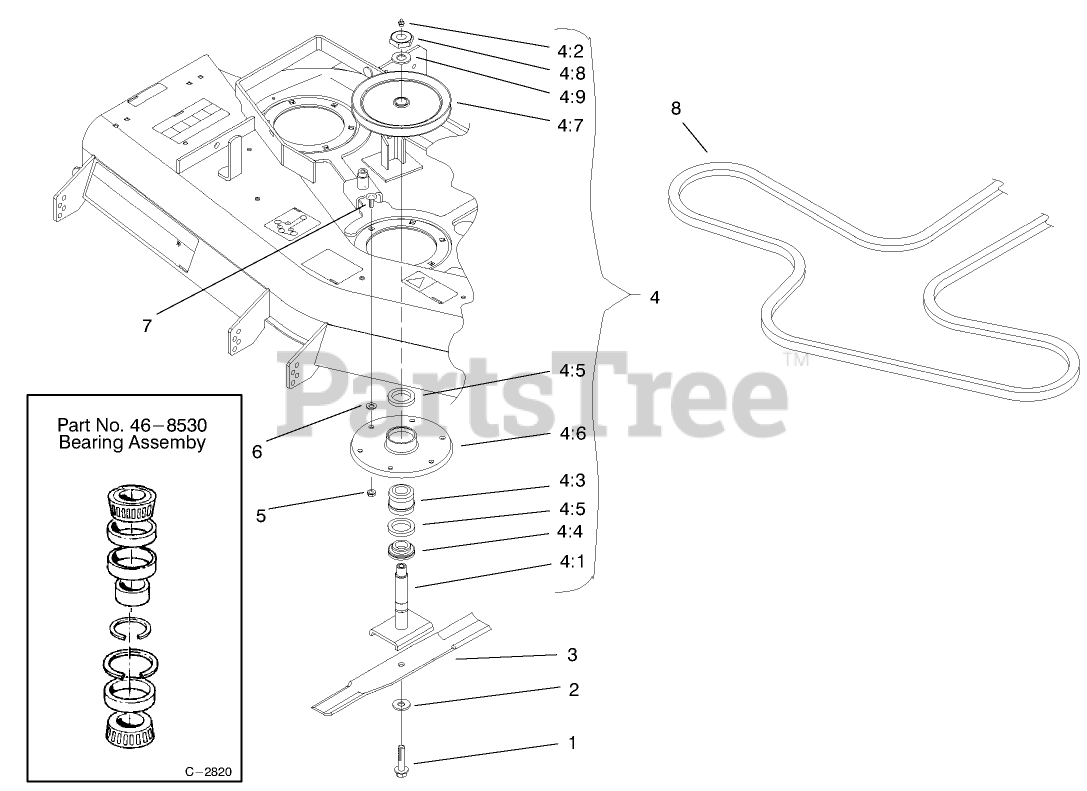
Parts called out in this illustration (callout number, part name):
1	BOLT-BLADE
2	Washer-Flat
3	BLADE-SAIL, EXTRA HIGH
4	SPINDLE HOUSING ASM
4:1	SPINDLE SHAFT ASM
4:2	FITTING-GREASE
4:3	BEARING ASM
4:4	SPACER
4:5	SEAL-OIL
4:6	HOUSING-SPINDLE
4:7	PULLEY AND HUB ASM
4:8	NUT-HEX
4:9	WASHER
5	NUT-HF
6	WASHER-FLAT
7	SCREW-CARR
8	BELT-DECK (52)
